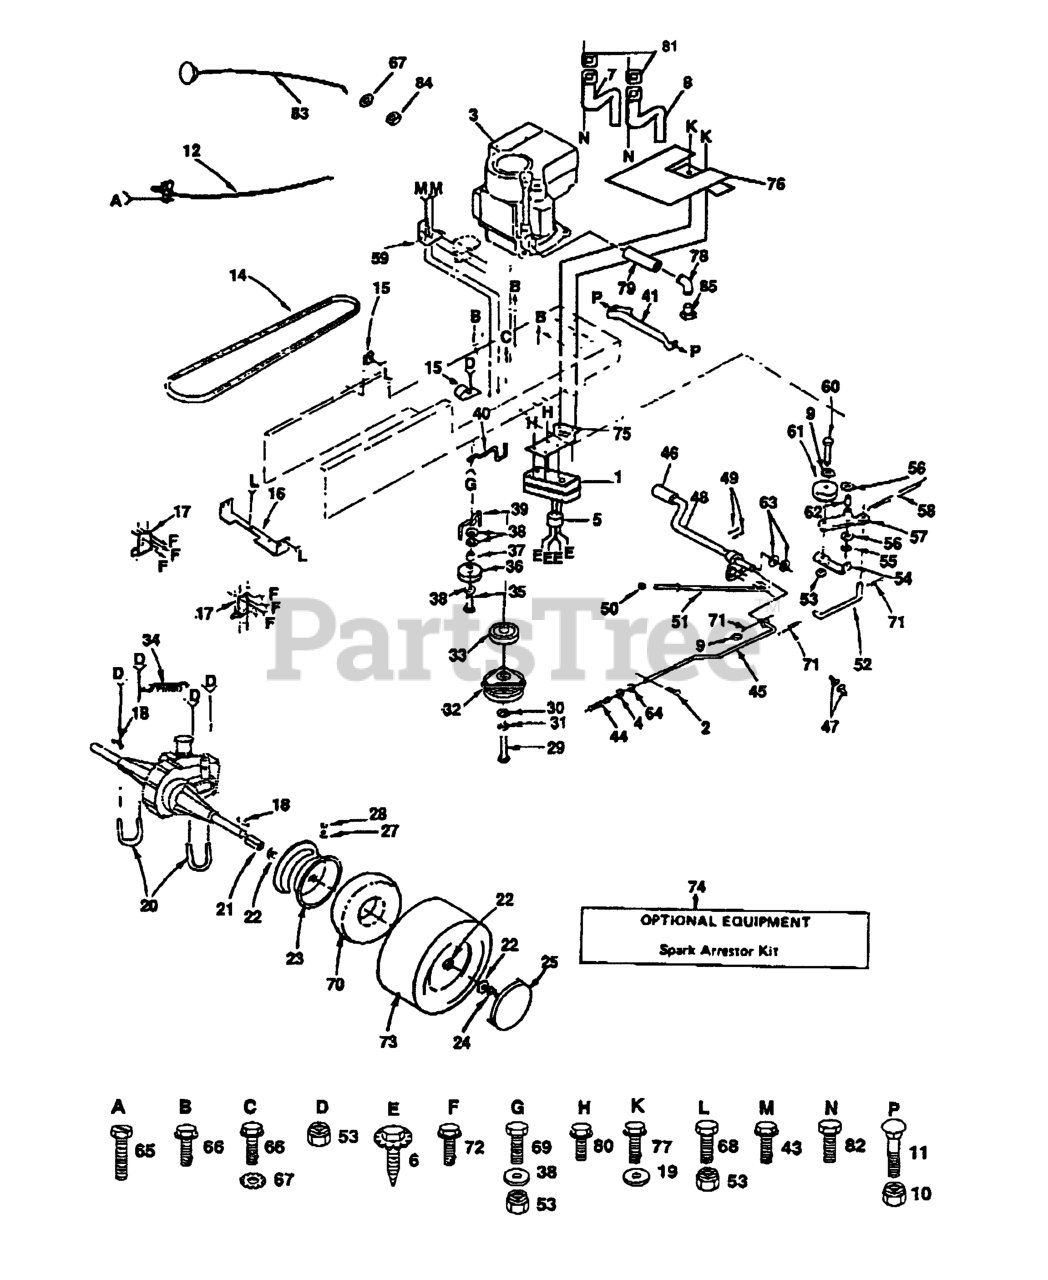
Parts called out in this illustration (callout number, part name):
2	RETAINER M
4	NUT
5	DEFL MUFFLER LTV
6	SCREW
7	TUBE ASSY EXH LH
8	TUBE ASSY EXH RH
9	WASHER
10	LOCKNUT
11	RP BOLT 5/16-18 X3/4 ZN/YEL GR
12	Control, Throttle
15	CLIP T
16	BRKT,MTG NLA
17	BRKT TRANSAXLE
18	SQUARE KEY
19	WASHER
21	SPACER SPLIT
23	RIM 8"
25	CAP,HUB REAR
27	VALVE STEM LT
29	Bolt, Hex, Fin 7/16-20 UNF x 4 Grade 8
31	LOCKWASHER
32	CLUTCH ELEC HYT
33	ENGINE PULLEY
34	SPRING T
36	FLAT IDLER PULLEY
38	WASHER
39	BELT KEEPER LT NLA
40	KEEPER, BELT
41	KIT RETAINER YTH
44	SPRING ROD LT
45	ROD BRAKE
46	COVER, PEDAL (1 2)
47	BEARING.NYLON
48	SHAFT FOOT PEDAL
49	DRIVE PIN
50	PLUNGER CAP
51	BRAKE PARK ROD
52	LINK, CLUTCH LT
54	RETAIN BELT
57	ARM IDLER
58	SPRING, RETURN LT
59	BRACKET LT
60	BOLT
61	IDLER PULLEY
62	BEARING LT (2 2)
63	WASHER LT
64	NUT
65	SCREW LT
66	SCREW LT
67	LOCKWASHER
69	BOLT
70	TUBE
71	COTTER PIN
72	SCREW
73	TIRE.TS.20X10-8
74	SPARK ARREST
75	BRACKET MUFFLER
76	HEAT SHIELD
77	SCREW.THDROL.5/16-18X3/4.TTY
78	ELBOW
79	Nipple, Pipe
80	SCREW ST
81	Gasket
82	Bolt, Metric
83	CHOKE CONTROL
84	NUT
85	Plug, Oil Drain
